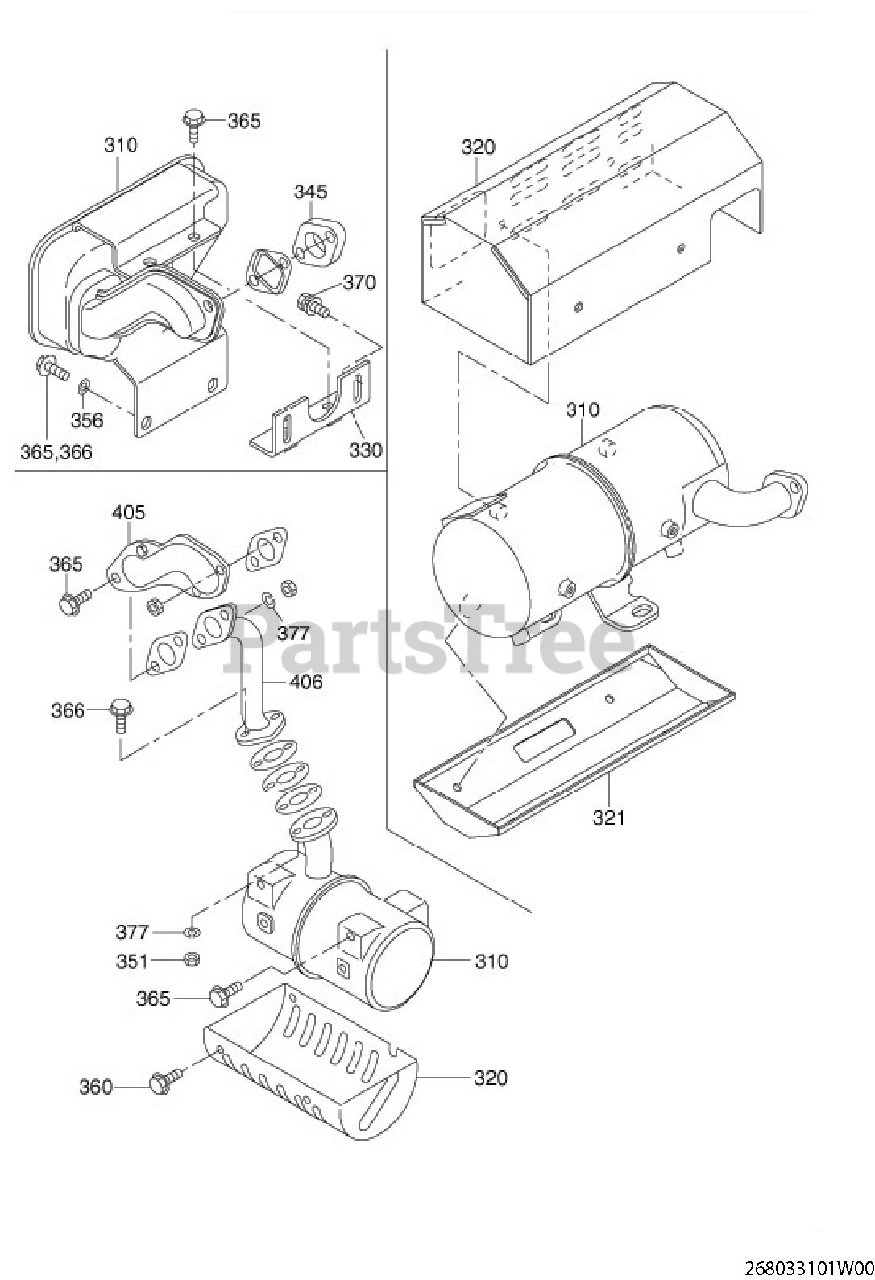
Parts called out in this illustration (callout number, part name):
345	SPACER (EXHAUST)
365	BOLT AND WASHER AY
370	BOLT AND WASHER AY
